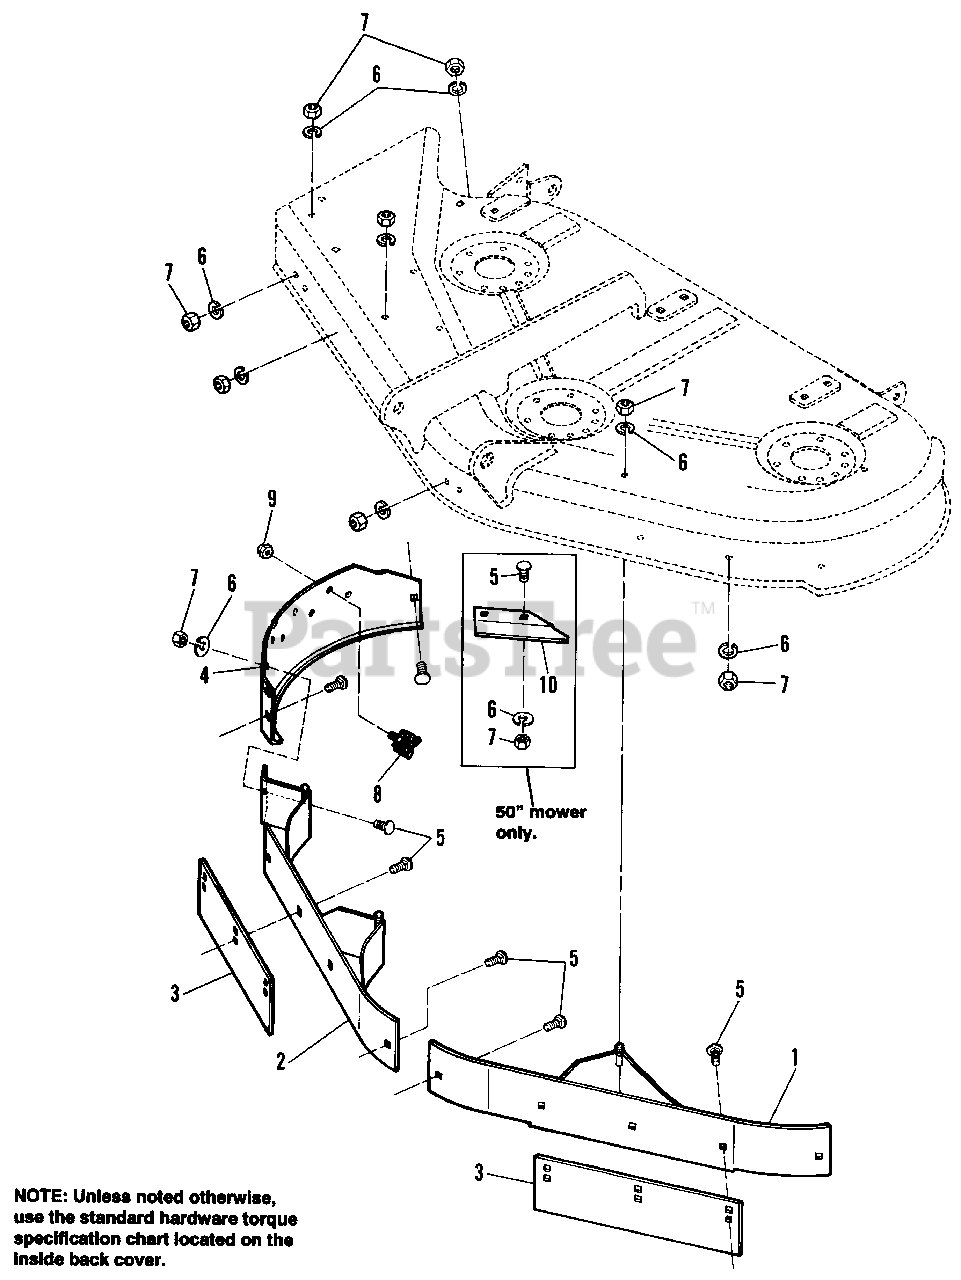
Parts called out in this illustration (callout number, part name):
1	BAFFLE, Front, L.H.
2	BAFFLE, Front, R.H.
3	Deflector, Rubber
4	BAFFLE, Discharge
5	CARRIAGE BOLT, 5/16-18 x 3/4
6	LOCKWASHER, 5/16
7	NUT, Hex, 5/16-18
8	LEAF SHREDDERS
9	NUT, Hex, Plastite, 5/16-18
10	MOWER LIP, Rear (50" Only)
